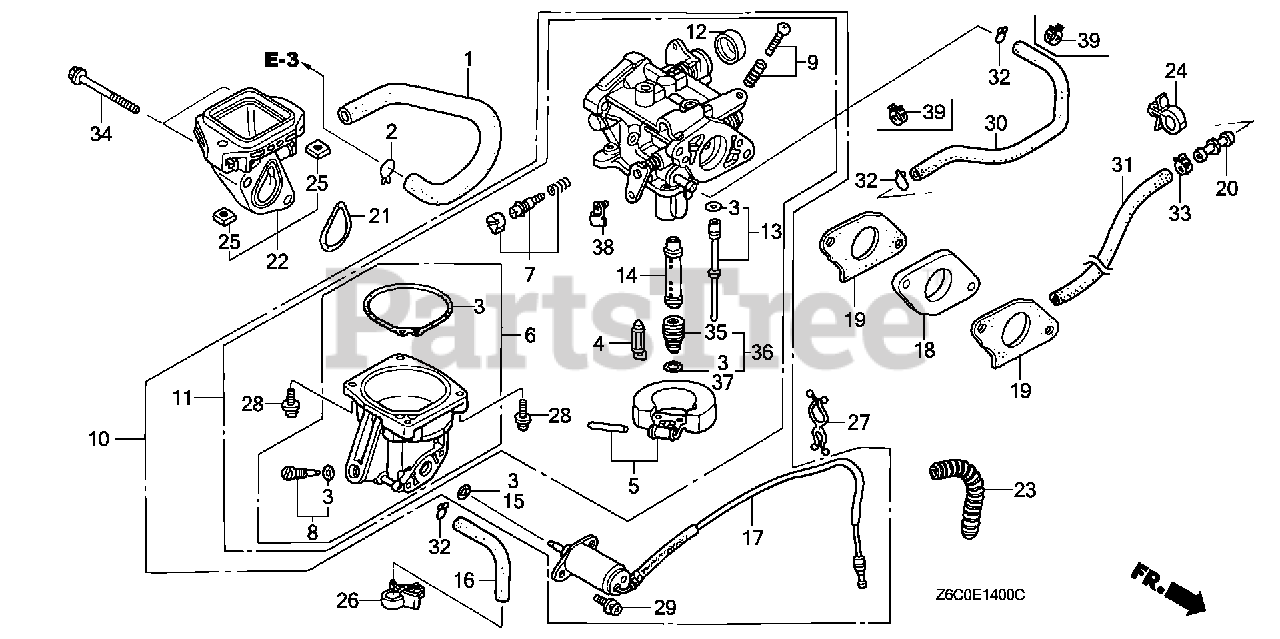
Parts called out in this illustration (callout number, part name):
1	TUBE, BREATHER
2	CLIP, BREATHER TUBE
3	GASKET SET
4	VALVE SET, FLOAT
5	FLOAT SET
6	CHAMBER SET, FLOAT
7	SCREW SET
8	SCREW SET, DRAIN (ADVENTURE GREEN) (CARBURETOR NO.)
9	SCREW SET
10	CARBURETOR ASSY. (BG21H C)
10	CARBURETOR ASSY. (BG21S A)
12	CAP, CHOKE LEVER DUST
13	JET SET (#58)
14	NOZZLE, MAIN
15	O-RING (5.8X1.9)
16	TUBE, DRAIN
17	VALVE ASSY., SOLENOID
18	INSULATOR, CARBURETOR
19	GASKET, CARBURETOR
21	GASKET, AIR CLEANER
22	ELBOW COMP., AIR CLEANER
25	NUT, INSERT (6MM)
26	CLIP B, CABLE
27	CLIP, PURSE LOCK
28	SCREW-WASHER (4X14)
29	SCREW-WASHER (5X12)
32	CLIP, TUBE (B8)
34	BOLT, FLANGE (6X120)
36	JET SET, MAIN (#88) Use up to Engine SN BG17A A.
36	JET SET, MAIN (#90)
38	ARM, THROTTLE LINKAGE (CARBURETOR NO.)
